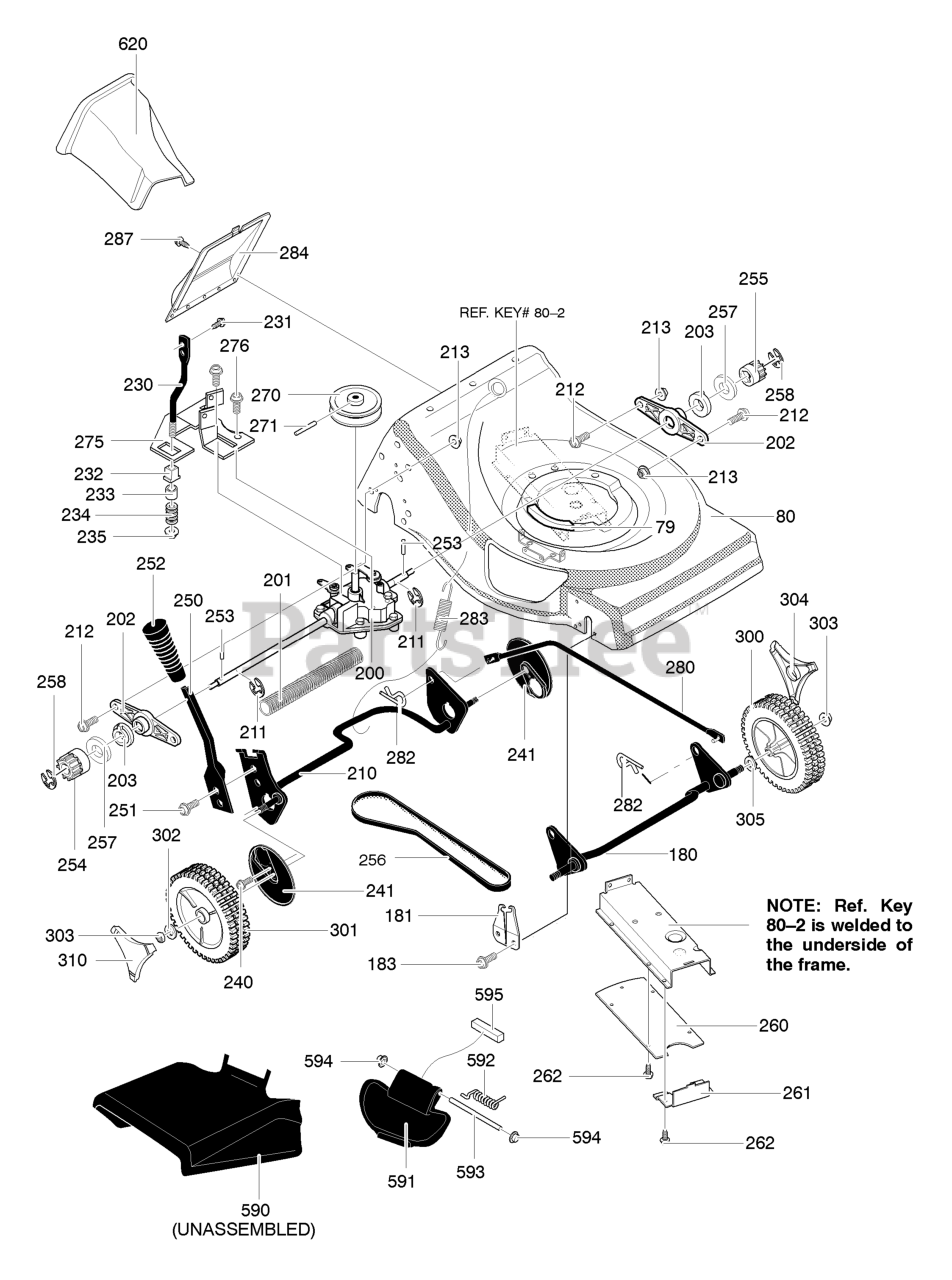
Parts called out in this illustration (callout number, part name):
79	SEAL, FOAM
80	ASSY, HOUSING
180	CROSSBAR, FRONT
181	BUSHING
200	TRANSMISSION, TUFF TORQ
201	SHIELD, AXLE
202	SUPPORT, AXLE
203	BEARING, LIFTER
210	ASSY, CROSSBAR
212	SCREW
213	NUT
230	SUPPORT, SPRING
231	SCREW
232	BUSHING
235	NUT, 5/16-18
241	DUST COVER
250	LEVER, SPRING
252	GRIP, HEIGHT ADJ
253	PIN, DRIVE
254	PINION RIGHT
255	GEAR, PINION LEFT
256	BELT, V
257	WASHER, FLAT
260	COVER, BELT GUARD
261	COVER, FRONT BELT
271	PIN, SPRING
275	BRACKET, CABLE
276	SCREW
280	LINK, LIFTER ASSY
282	PIN, HAIR
283	SPRING, EXTENSION
284	COVER, REAR
300	TIRE & RIM, -FRONT
301	WHEEL, DRIVE - RR
302	WASHER, FLAT
303	NUT
304	HUB CAP
305	WASHER
310	HUB CAP
590	DEFLECTOR, CHUTE
591	COVER, MULCH
592	SPRING, TORSION
593	ROD, PIVOT
594	CAP, PUSH ON
595	SEAL, FOAM
620	PLUG, MULCHER
